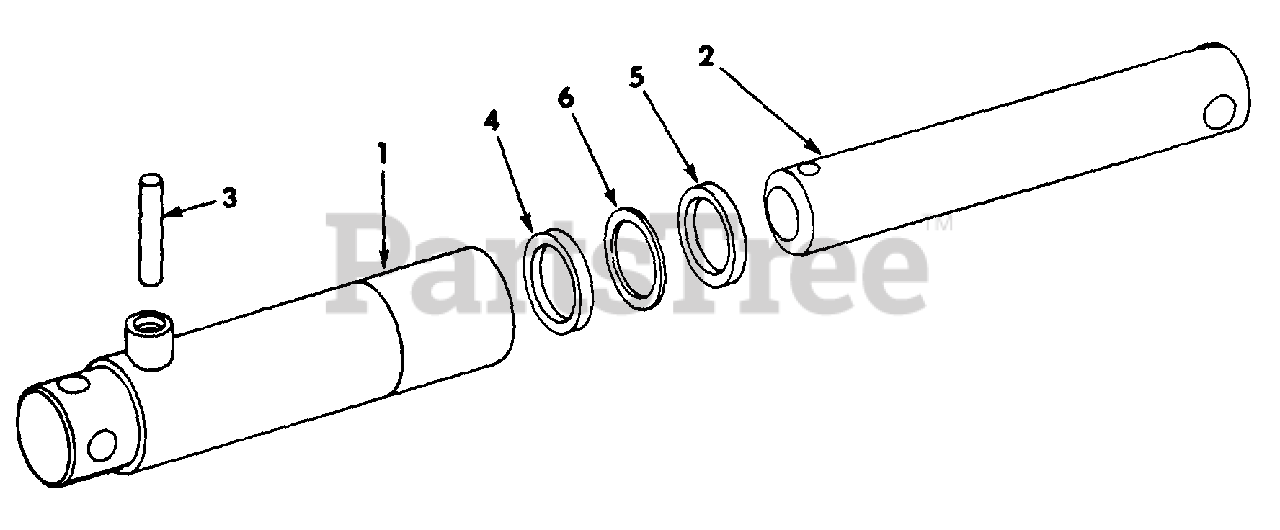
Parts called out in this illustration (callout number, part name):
1	BODY ASSY, HYD CYLINDER
5	WIPER, PISTON ROD
6	WASHER, PISTON ROD BRACKET
